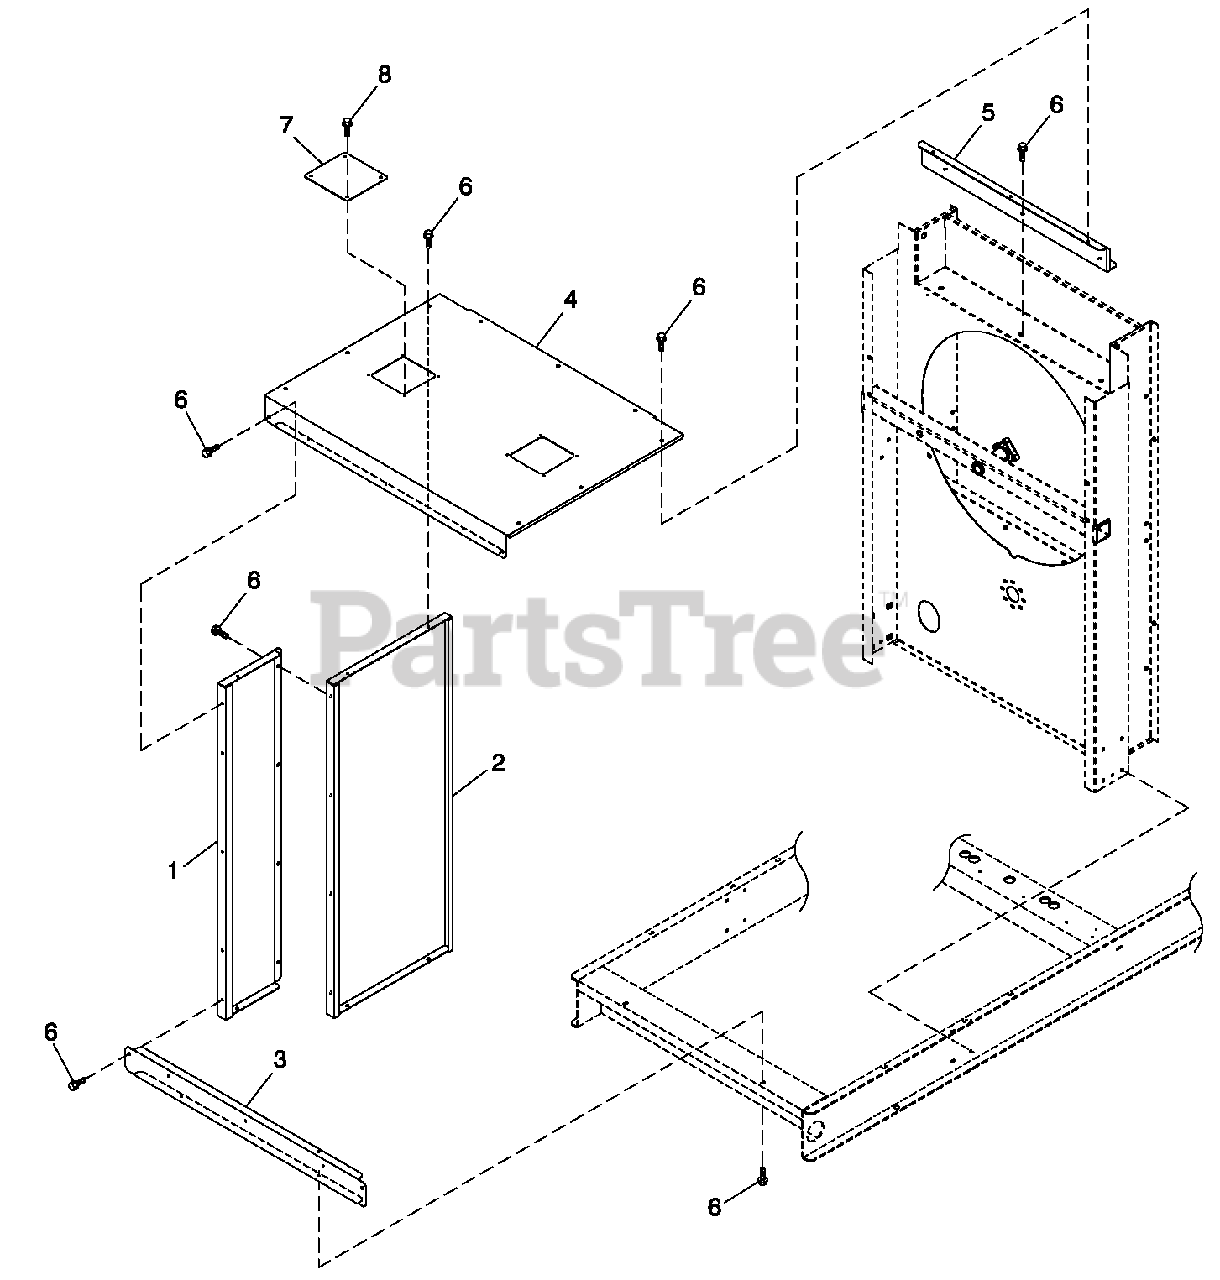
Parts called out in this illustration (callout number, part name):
1	WELDMENT RADIATOR SUPPORT C5
2	RADIATOR 680 X 680 X 70 CPL
3	V-BELT 31/64" X 62-3/8"
4	WASHER LOCK M10
5	SCREW HHC M10-1.5 X 30 C10.9
6	SCREW THF M6-1 X 16 N WA Z/JS
7	TAPE FOAM 1 X 1 (26.75" LG)
8	TANK COOLANT RECOVERY
9	PULLEY FAN V-GROOVE 9"
10	FAN 26" LH ROTATION
11	ARM BELTTENSIONER
12	SHOULDER BOLT 1/2 X 2-1/4"
13	SPRING TENSION CPL
14	PULLEY V-BELT 4" FLANGED
15	WASHER FLAT 3/8-M10 ZINC
16	SCREW HHC M8-1.25X45C8.8
17	SCREW HHFC M6-1.0X20 G8.8
18	HUB FLEX PLATE
19	NUT HEX LOCK 5/16-24 NY INS
20	SCREW HHC M12-1.5X60G8.8
21	DISK FLEX
22	COUPLING HUB FLEX (MACH)
23	CLAMP HOSE BAND 1/4
24	SCREW HHC 5/16-24X1.124
25	KEY WOODRUFF 4X 1 9D
26	HOSE RADIATOR UPPER CPL
27	HOSE LOWER RAD CPL C5 6.8L
28	ASSY BRG/SHAFT CPL FANDRIVE
29	PULLEY 6.5" DIA MACHINED (6.8L 100KW)
30	SCREW HHC M10-1.5X30G8.8
31	SCREW HHC 1 /2 -1 3X2 " G8
32	WASHER FLAT 1/2 ZINC
33	WASHER LOCK 1/2
34	NUT HEX 1/2-13 STEEL
35	NUT HEX M6X 1.0 G8 YEL CHR
36	WASHER NYLON .50 X .87 X .06
37	CAP RADIATOR 13 PSI
38	BRACKET, SIGNAL CONDITIONER
39	WASHER FLAT 5/16-M8 ZINC
40	WASHER LOCK M8-5/16
41	SPACER .5 X 1.5 X .25 STL/ZINC
42	CLAMP HOSE #28 1.32-2.25
43	SCREW HHTT M4-0.7 X 8 BP
44	SPRING CLIP HOLDER .37-.62
45	CLAMP HOSE .38-.87
46	BARBED STR 3/8 NPT X 3/8
47	HOSE DRAIN ASSY 28"
48	CAP HEX 1/4 NPT BRASS
49	BRACKET COOLANT TANK
50	WASHER FLAT 1/4-M6 ZINC
51	WASHER LOCK M6-1/4
52	SCREW HHC M6-1.0X20G8.8
53	SHIELD RADIATOR
54	SCREW HHC M8-1.25X20G8.8
55	WASHER LOCK M12
56	WASHER FLEX (THIN)
57	PROBE COOLANT LEVEL 3/8-18NPTF
58	BRACKET TENSIONER SPRING
59	HOSE 9/32 ID (43" LG)
60	NUT HEX LOCK M8-1.25 NY INS
61	BEARING SLEEVE 1/2/ X 3/4 X 1
62	SPACER CPL COOLING FAN 1/8"
63	SCREW HHC M10-1.5X20C8.8
64	SCREW SHC M10-1.5X 35 G12.9
